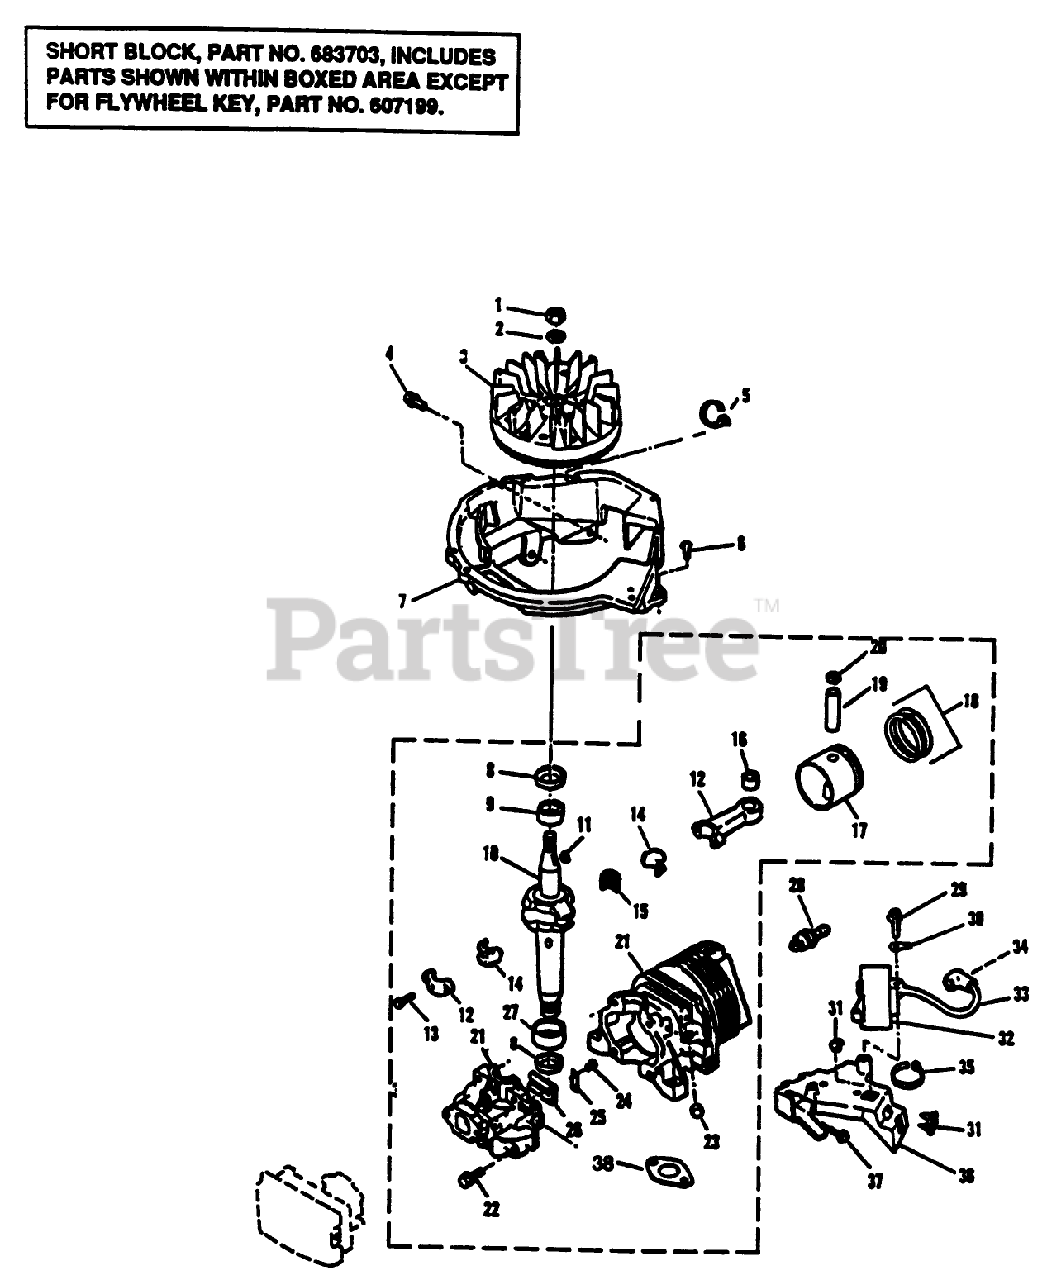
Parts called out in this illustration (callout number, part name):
1	NUT
4	SCREW-SEMS
6	SCREW F
8	SEAL-OIL
9	BEARING V
11	KEY
13	SCREW-HSH
14	LINER ASM
15	BEARING-NEEDLE
16	BEARING AY F
17	Piston Ring Set (Inc. 18-20)
20	RING-RETAINING
22	SCREW-H.W.HD. F
23	PLUG-CORE VF
24	SCREW-HH
25	PLATE-BACKUP, REED
27	BEARING V
28	SPARK PLUG
30	TERMINAL S
31	NUT-CLIP
33	HT LEAD&COVER XEV
34	COVER & TERM. AY S
35	TIE-CABLE
36	C.D. BRKT F
37	SCREW F
